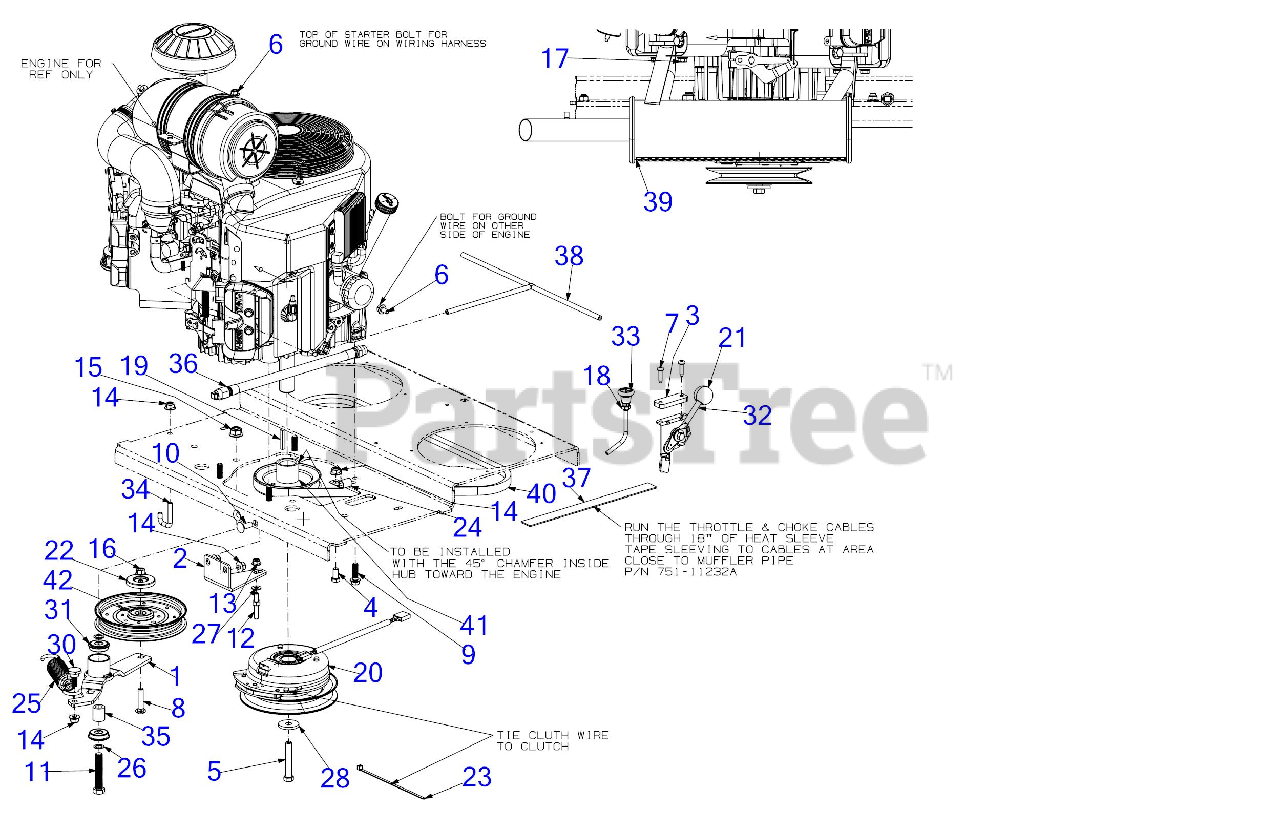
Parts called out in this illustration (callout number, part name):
4	HEX SCREW 3/8-16 x .75
5	SCREW 7/16-20:2.75 GR5
6	SCREW M8 x 1.25 x 16MM GR8.8
7	SCREW 1/4-20 x 1.0
8	CARRIAGE BOLT 3/8-16 x 1.75 GR5
9	SCREW 3/8-16 x 1.25 GR5
10	CARRIAGE BOLT 3/8-16 x 1.00 GR5
11	SCREW 1/2-13 x 2.75 GR5
13	FLANGE LOCK NUT 5/16-18
16	HEX LOCK NUT
17	HEX FLANGE NUT
18	HEX JAM NUT 3/8X24
19	SQUARE KEY 1/4 x 1.50
20	ELECTRIC PTO CLUTCH
20	CLUTCH HARNESS 11.625
22	PULLEY CAP
23	7" CABLE TIE
24	J TYPE CLIP
25	EXTENSION SPRING W/HOOK
26	WASHER .510 x .750 x .033
27	FLAT WASHER
28	FLAT WASHER .45 x 1.5 x .172 HT
30	SHOULDER SCREW .625 x .302 x 3/8-16
31	ROLLER BEARING .5X1.37X.44
32	THROTTLE CABLE 59"
33	CHOKE CABLE
34	ROD SPRING HOOK
35	SPACER 0.51 X 0.88 X 1.00
36	OIL DRAIN HOSE
38	ROLLOVER VENT HOSE ASSEMBLY
39	KAWASAKI MUFFLER
40	TRANSMISSION BELT 61.5
41	PULLEY - PUMP DRIVE
42	IDLER PULLEY
